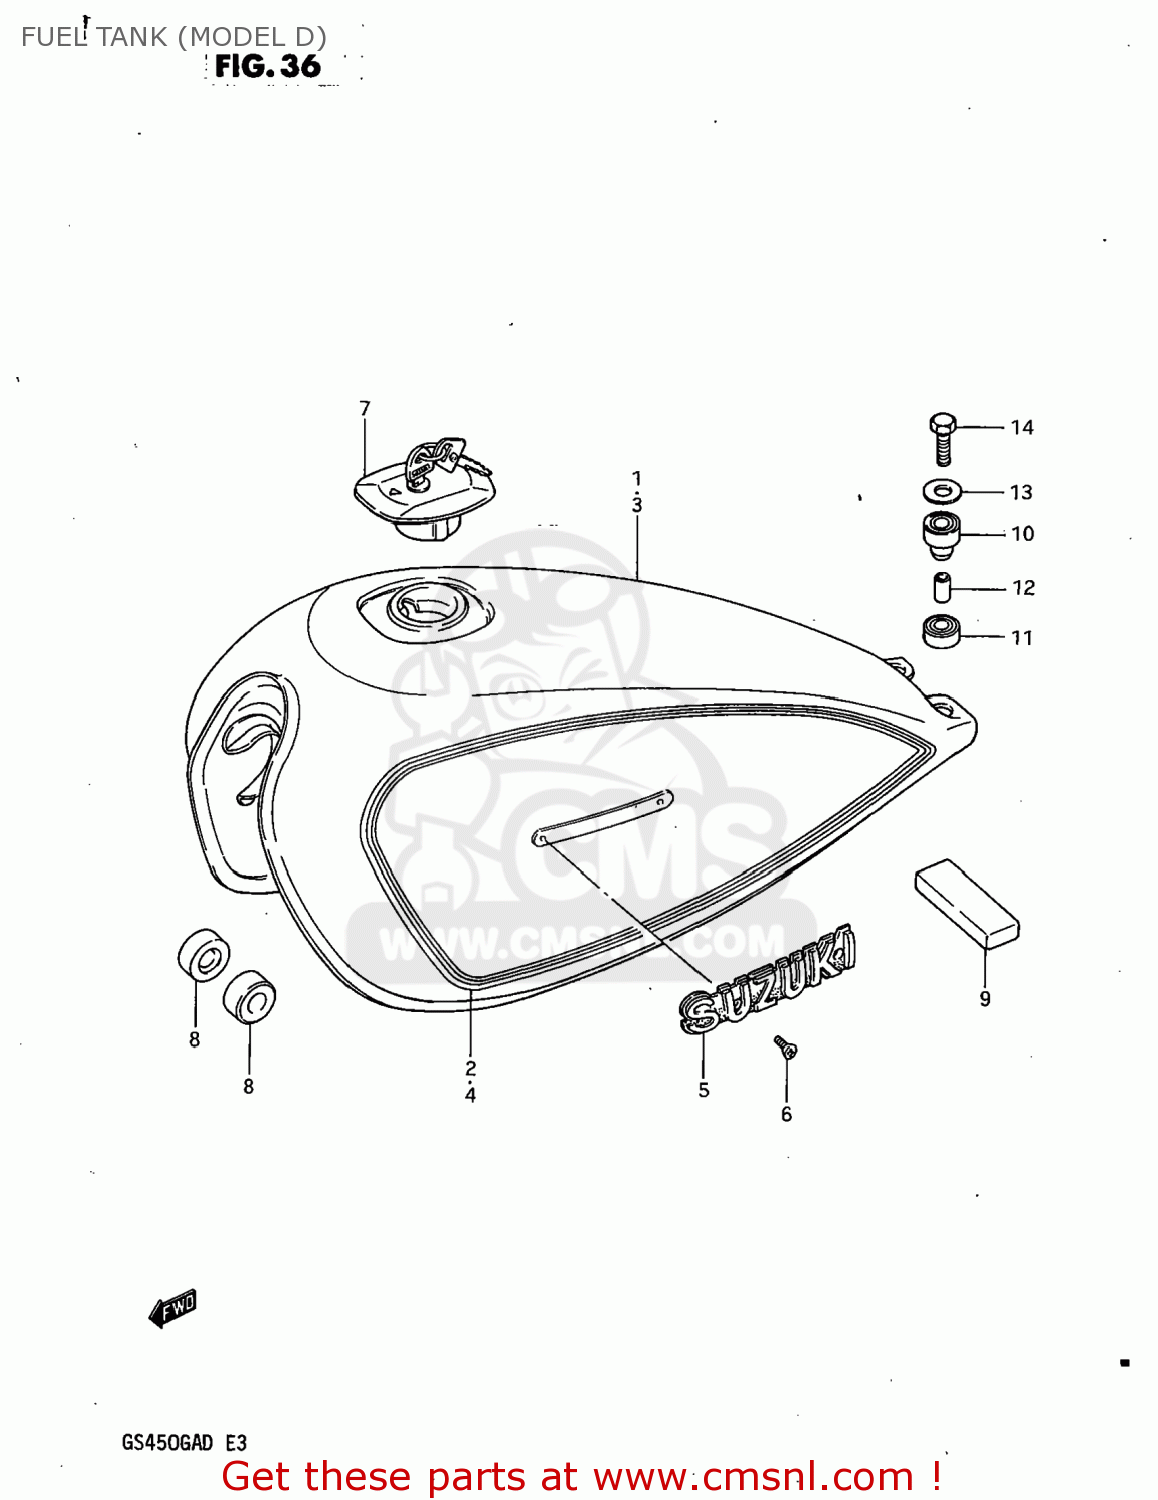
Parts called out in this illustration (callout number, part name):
1	TANK ASSEMBLY,FUEL
2	TAPE SET,FUEL TANK
3	TANK ASSEMBLY,FUEL
4	TAPE SET,FUEL TANK
5	EMBLEM,FUEL TANK
6	SCREW 3X6
7	CAP SET,FUEL TANK
8	CUSHION
9	CUSHION
10	CUSHION
11	CUSHION
12	SPACER (6.4X9X20)
13	WASHER (6.5X24X1.6)
14	BOLT
